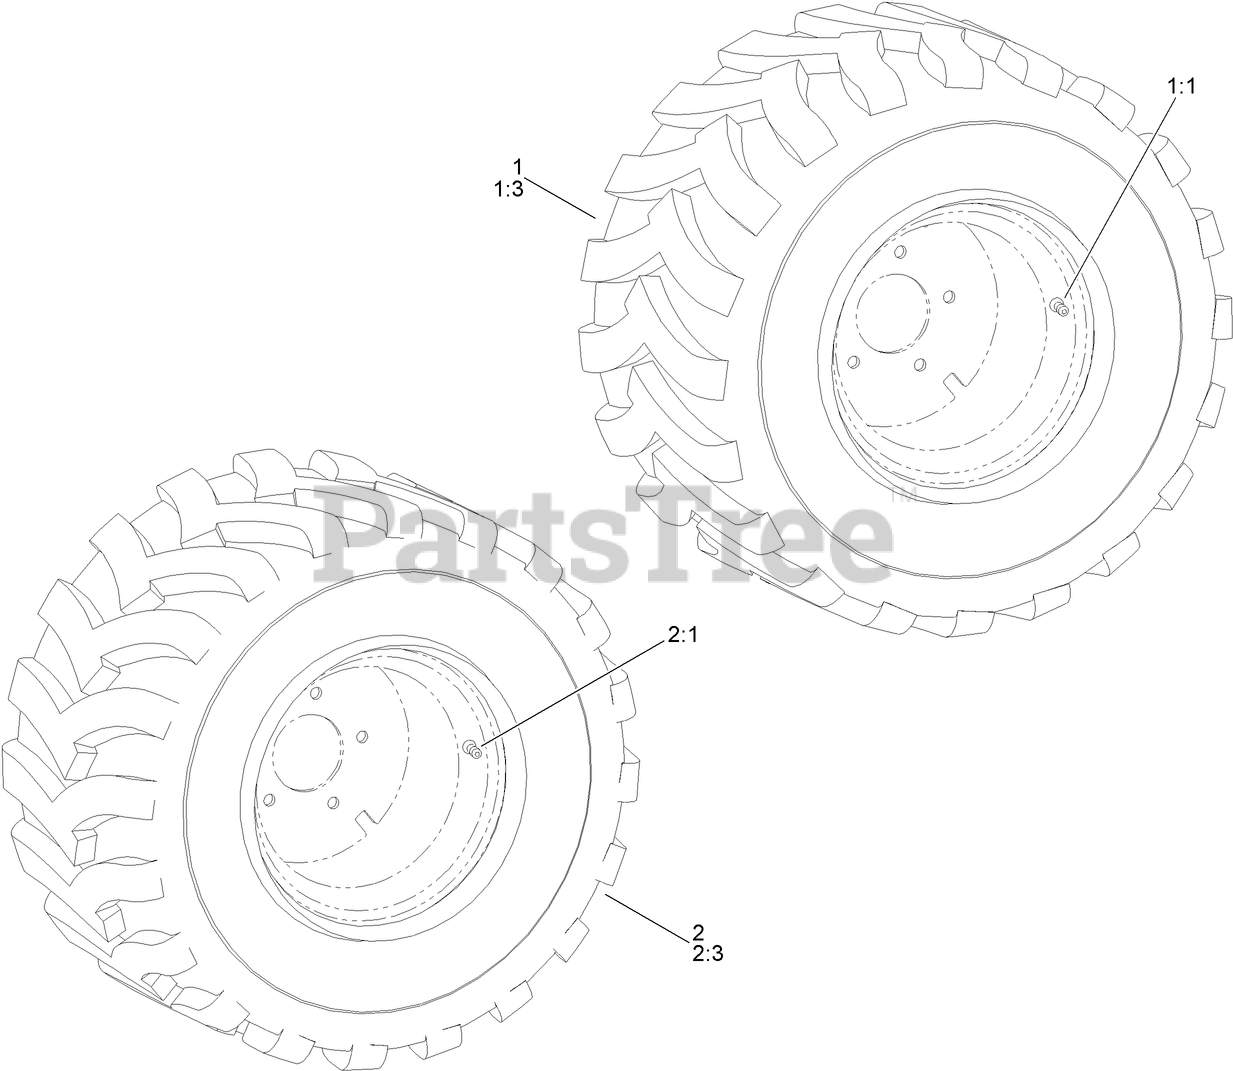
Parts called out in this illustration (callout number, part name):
1	RH WHEEL AND TIRE ASM
1:1	STEM-VALVE
2	LH WHEEL AND TIRE ASM
2:1	STEM-VALVE
